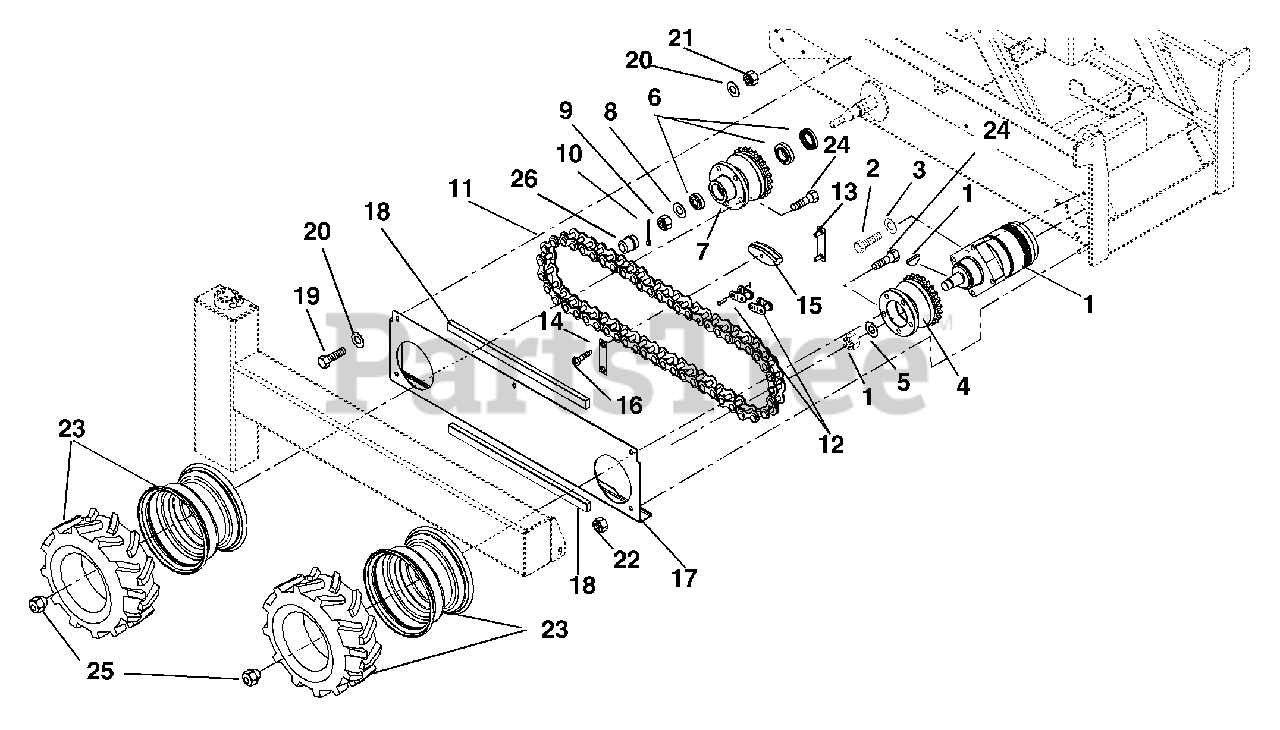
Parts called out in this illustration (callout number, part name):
1	Motor-Wheel
1	Seals, Hydraulic Motor
1	Seals, Hydraulic Motor Hi-Temp
2	Bolt-Hex M16-2 x 40 Class 10.9
3	Washer-Flat-Steel .63 x 1.005 x .062
4	Hub-Front Drive
5	Washer-Flat-Steel 1.062 x 2.0 x .134
6	Bearing-Wheel Set
7	Hub-Rear Idler
8	Washer-Hardened-Thrust .758 x 1.23 x .031
9	Nut-Slotted .75-16
10	Pin-Cotter.12 x 1.25
11	Chain-60 Roller
12	Link, Master Half
13	Bracket-Chain Tensioner
14	Bracket-Retainer Plate
15	Guide-Chain Tensioner
16	Screw-Socket Flat Head M8-1.25
17	Guard-Chain Right Hand
17	Guard-Chain Left Hand
18	Gasket-Foam with Adhesive Back
19	Bolt-Hex M8- 1.25 x 16
20	Washer-Flat-Steel .344 x .688 x .065
21	Nut-Locking-Nylon M8-1.25
22	Nut-Locking-Nylon M10-1.5
23	Wheel-Lug Assembly Right Hand
23	Wheel-Lug Assembly Left Hand
23	Tire-Lug 20 x 8.00-10
23	Tube-20 x 8.00-10
24	Bolt-Wheel Lug .44-20 x 1.38
25	Nut-Lug .437-20
